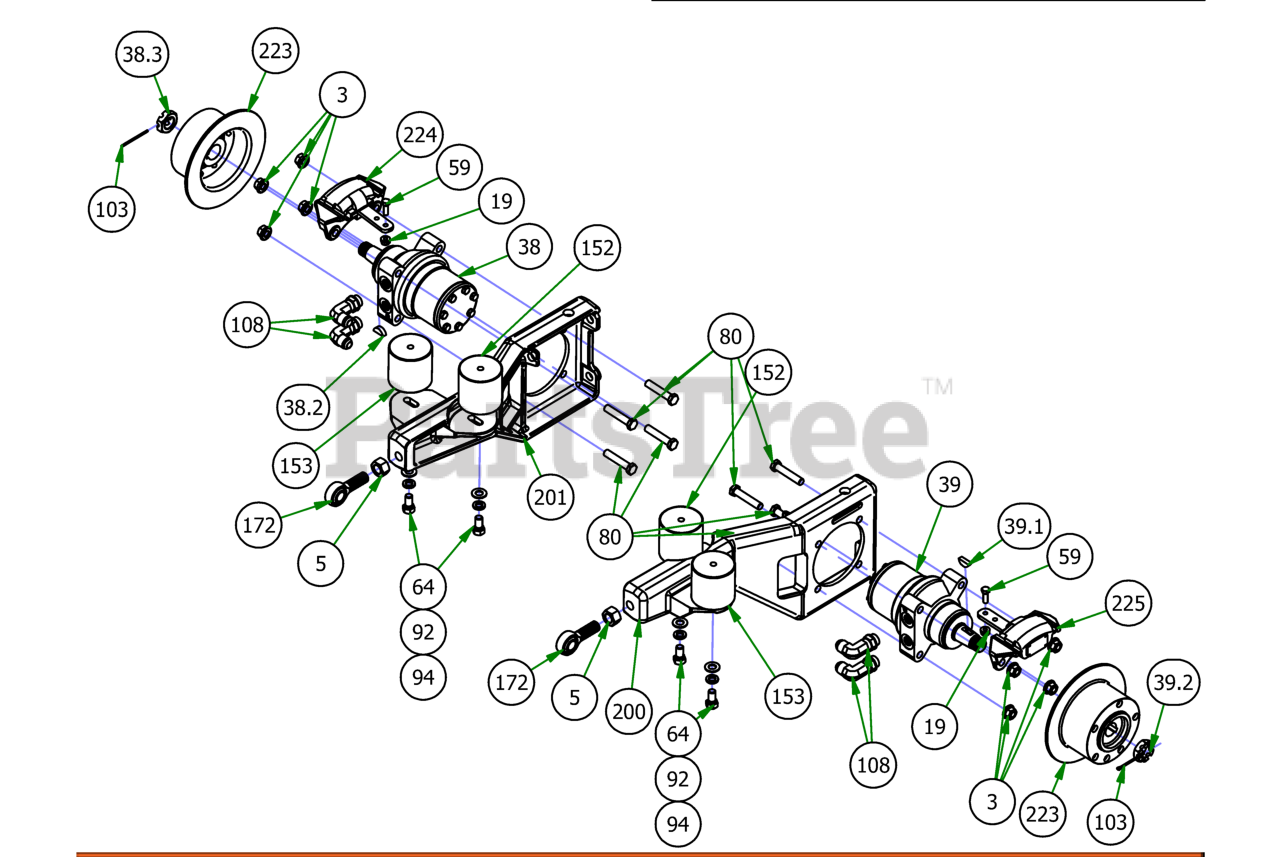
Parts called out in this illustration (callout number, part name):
3	1/2-13 Gr 8 Centerlock Flange Nut
5	3/4"-16 Fine Full Nut
6	3/4" Course Thread Nylon Lock Nut
16	5/8 Std NC Nylock Nut
19	5/16-18 Nylon Flange Nut
38	18cc Parker Wheel Motor- Right
38.2	Woodruff Key
38.3	1" Castle Nut for Wheel Motor
39	18cc Parker Wheel Motor- Left
39.1	Woodruff Key
39.2	1" Castle Nut for Wheel Motor
49	3/4 x 2 1/2 Course Thread Bolt
50	AS 2465 - 5/8 x 2 3/4 UNC
59	5/16" x 1" Bolt
64	1/2" x 1" Hex Bolt
80	1/2-13 x 2.75 Gr. 8 Hex Head Bolt
81	5/8" x 2 1/2" Grade 5 Hex Bolt (Coarse)
83	1/2-20 x 1-1/2 Lug Bolts Zinc
90	5/8" Flat Washer SAE Spec Grade 8
92	1/2" Lock Washer
94	1/2" Washer (Grade 8)
103	1/8x2-1/4 cotter pin Zinc
105	2019 Assy-26x12-12 Reaper Turf -10.5" Rim
105.1	2019 10.5" Wheel
105.2	2019 26x12-12 Reaper Turf Tire
108	2019 Rouge/Renegade Wheel Motor 90* Fitting #6801-10L
116	Spacer 1.125OD x .625 ID x .250 Length
121	5/8" x 1/" Collar W/One Set Screw
152	Vibration Mount-Blue Dot
153	Vibration Mount-Green Dot
160	2019 Suspension Gusset Outlaw
170	2019 Suspension Radius Rod Assembly
170.1	5/8-11 HEX JAM NUT ZINC
170.2	NUT, 5/8-18LH
170.3	2019 Suspension Link Body
170.4	2019 RH 5/8" Heim
170.5	2019 LH 5/8" Heim
171	2019 Suspension Radius Rod Assembly
171.1	3/4-16 HEX JAM NUT ZINC
171.2	3/4-16 LH HEX JAM NUT ZINC
171.3	Rear Radius Rod, 3/4 Body
171.4	3/4-16 x 5/8 RH Heim
171.5	3/4-16 x 5/8 LH Heim
172	3/4-16 RH Male Rod End
200	2019 Left Trailing Arm
201	2019 Right Trailing Arm
204	2019 Renegade Gas Frame - Powdercoated
223	Brake Disk
224	XP/AOS Right Brake Caliper
225	XP/AOS Left Brake Caliper
